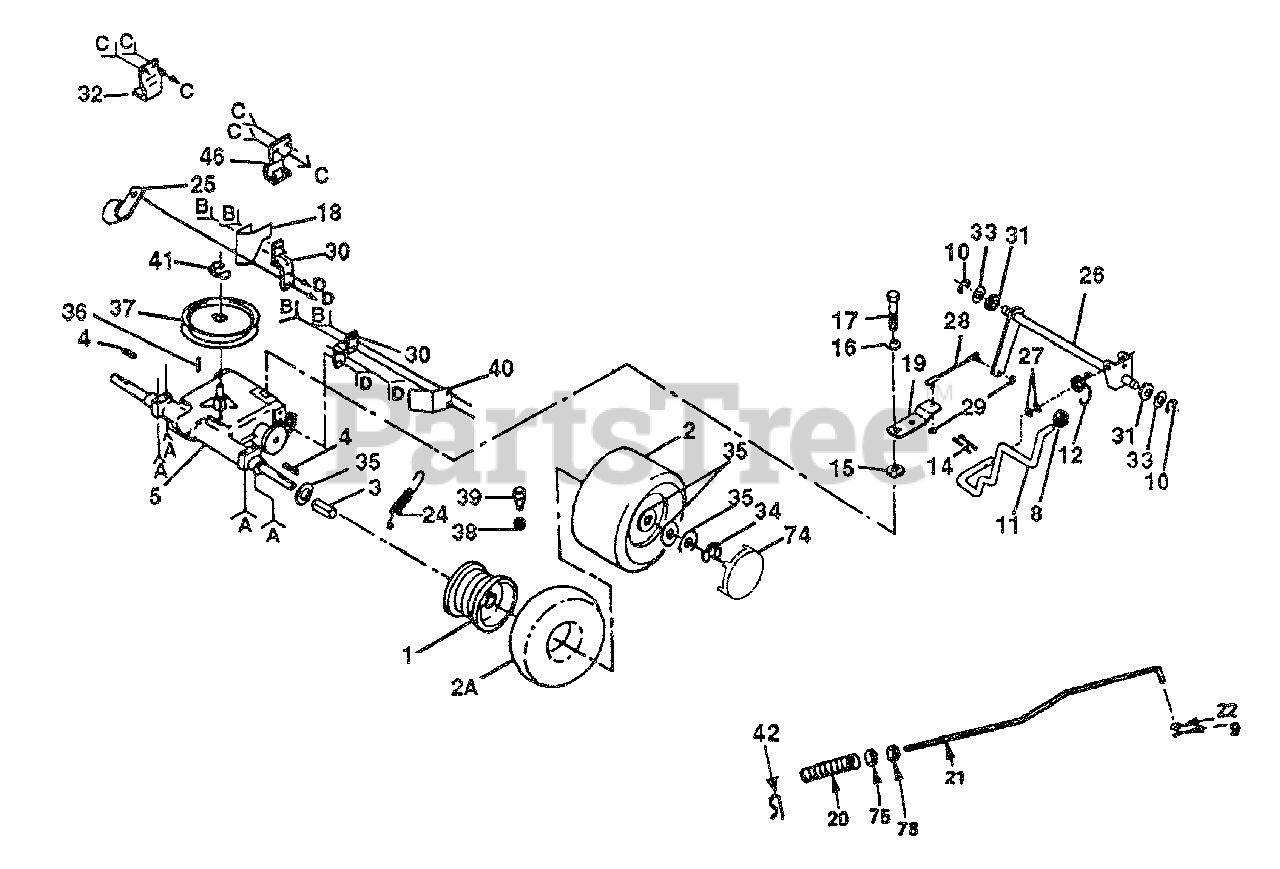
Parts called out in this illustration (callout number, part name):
1	Rim Assembly 8" Rear
2	Tire
2A	Tube-Tire
3	Spacer-Split
4	Key-Square 1/4 x 2
5	Transaxle 6 speed, Peerless Model No. 143.820-016
8	Knob Control
9	Cotter Pin 1/8 x 3/4
10	Ring, Klip
11	Rod-Shifter
12	Spring-Torsion
14	Pin, Cotter 1/8 x 1
15	Washer-Shift Plate
16	Washer 9/32 x 3/4 x 16 Ga.
17	Bolt-Hex 1/4-28 x 3/4, Gr. 8
18	Keeper, Belt Transaxle L.H.
19	Arm, Shift
20	Spring-Rod, Brake
22	Washer 13/32 x 13/16 x 16 Ga.
24	Spring, Brake Return
25	Clip
26	Shaft, Arm Shifter
27	Washer 17/32 x 3/4 x 16 Ga.
28	Rod, Tie
29	Nut 1/4-28
30	Strap-Torque
31	Bushing, Steering Rod
32	Bracket-Transaxle L.H.
33	Washer 21/32 x 1-1/4 x 16 Ga.
35	Washer 1-1/32 x 1-5/8 x 16 Ga.
36	Woodruff Key 3/16 x 3/4
37	Pulley, Transaxle
38	Cap, Valve
39	Stem-Valve
40	Keeper, Belt Transaxle R.H.
41	Ring, Retainer
42	Clip, Hairpin
46	Bracket, Transaxle R.H.
74	Cover, Wheel
75	Locknut, Hex Washer Insert 3/8-16
78	Nut-Hex Jam 3/8-16
